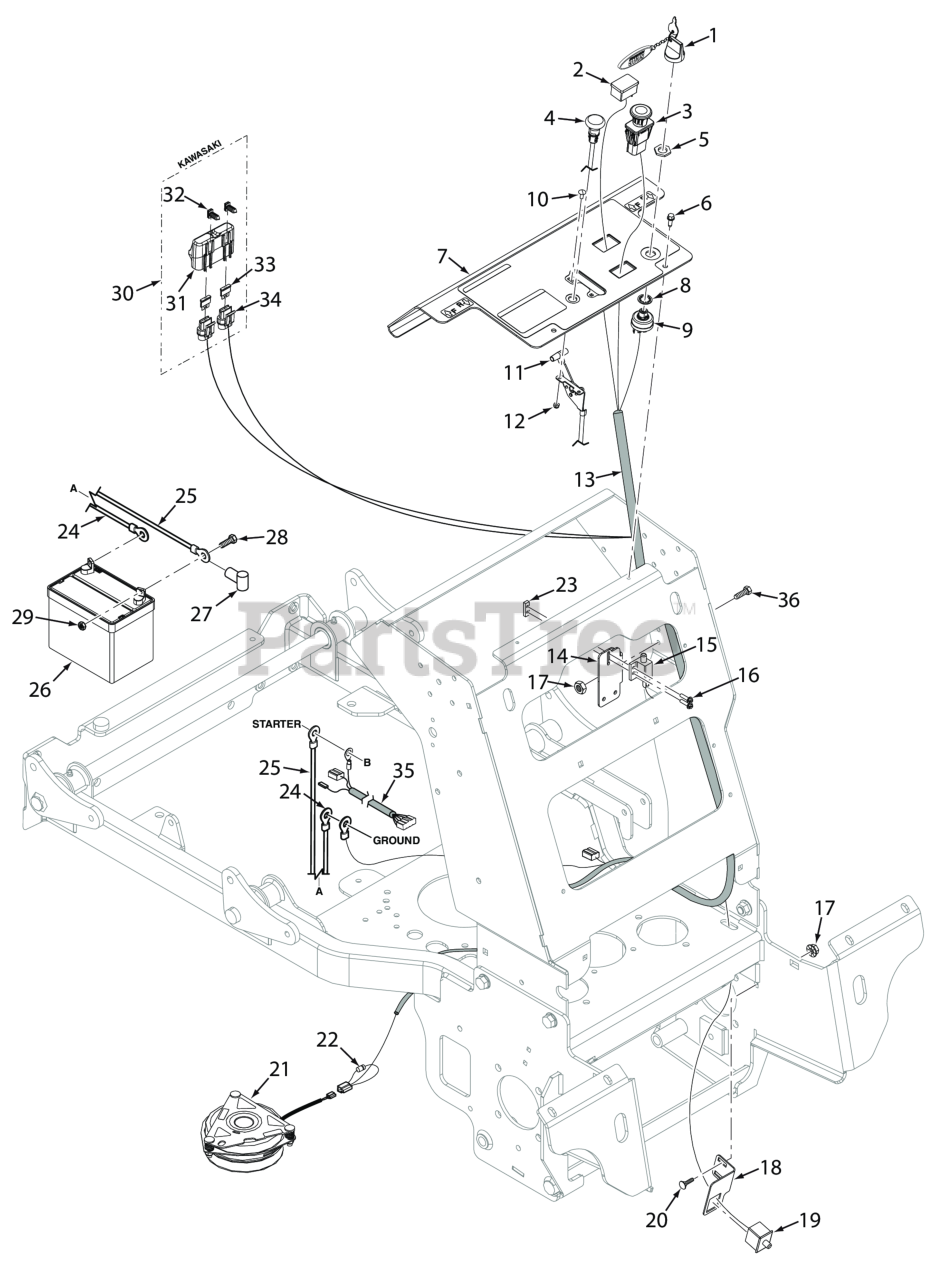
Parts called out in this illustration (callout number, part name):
1	Key, Assembly w/Fob
2	Hour Meter, Inductive
3	Switch, PTO - 10 Amp
4	Choke Control (excludes EFI models)
5	Nut, 5/8-32 Special
6	Screw, Self-Tapping 1/4-20 x 3/4
7	Instrument Panel w/Decal - SVRII36
8	LOCK WASHER, 5/8" INTERNAL TOOTH
9	KEY SWITCH(INCLUDES MOUNTING HARDWARE)
10	Bolt, Carriage #10-24 x 1/2"
11	Throttle Control, SVR
12	Nut, Elastic Stop #10-24
13	Wire Harness, SVRII-36
14	Bracket, Neutral Switch
15	Switch, Interlock (see below)
16	Screw, Hex-Slotted Washer Head #10 32 x 3/4"
17	NUT, 1/4-20 SERRATED FLANGE HEX HEAD
18	Switch Bracket, OPC Switch -SVRII-36
19	Switch, Double Pole OPC - SVRII-36
20	Serr. Fl. Hex Head CPSCR, 1/4-20 x 3/4"
21	Clutch w/Tag GT2.5-FE02 (48 / 52)
22	Diode, 600V 6 Amp
23	Plate, Threaded
24	Battery Cable, 39" Black (26EFI) - Kohler
25	Battery Cable, 44" Red w/Braid (26EFI) - Kohler
26	Battery, 350 CCA (not available through Scag)
27	RUBBER BOOT
28	BOLT, HEX HEAD, 1/4-20 X 3/4 GR.5
29	Nut, 1/4 - 20 Hex
30	Double Fuse Assy.
31	Cover, Sealed Double
32	Clip, Fuse Holder
33	FUSE, 20 AMP BLADE TYPE AUTOMOTIVE
34	Fuse Holder Assembly
35	Adaptor, Wiring Harness (Kawasaki only)
35	Wire Harness Adapter, Kawasaki - 22FX & 23FX
36	BOLT, HEX HEAD, 1/4-20 X 3/4 GR.5
